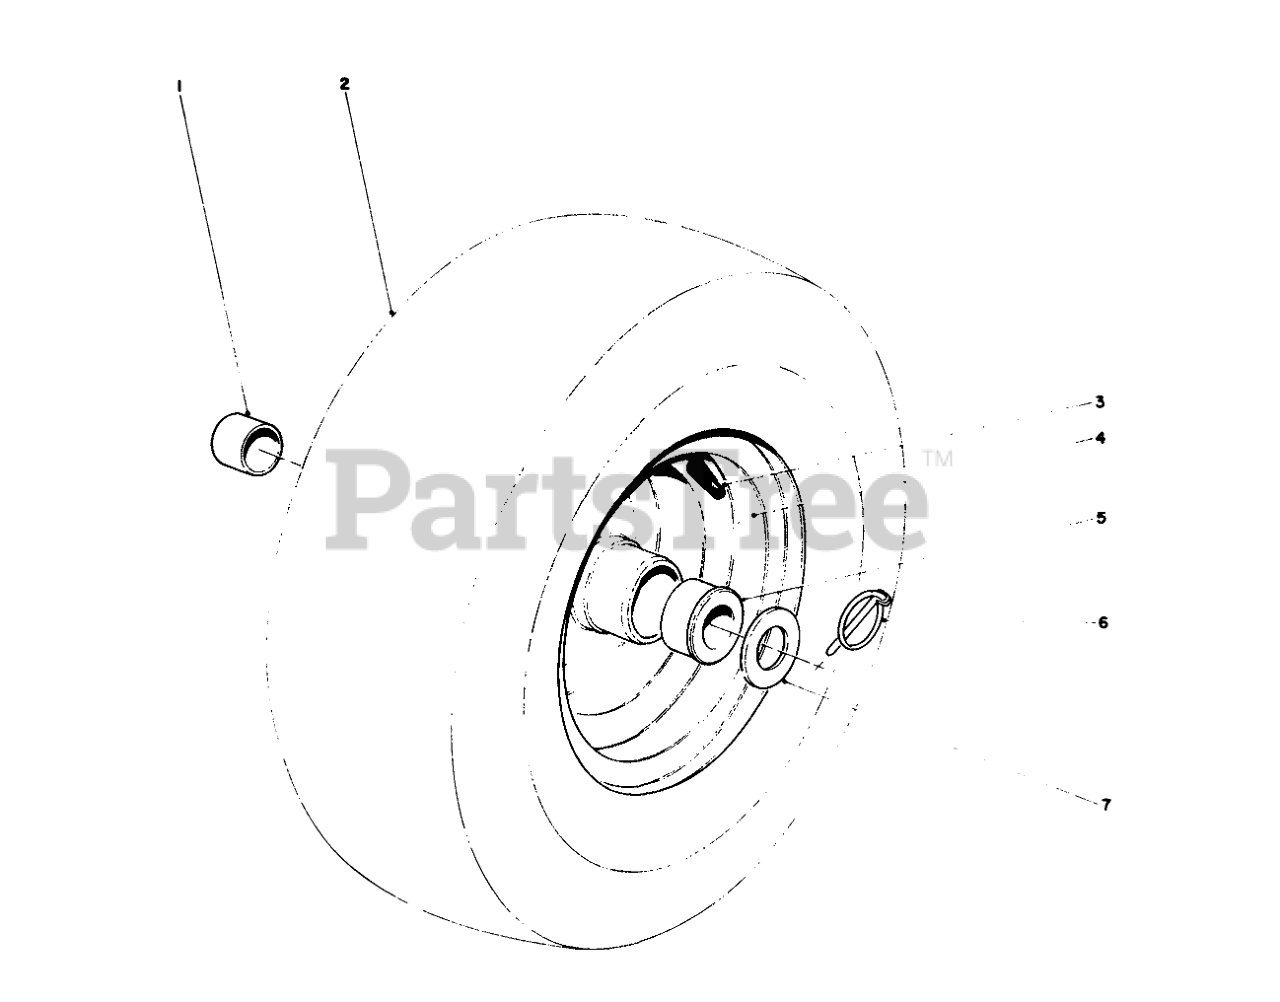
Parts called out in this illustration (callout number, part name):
1	.877ID X .750LG BSHG
2	Tire
3	STEM-VALVE
4	Wheel & Hub Assembly (Incl. Ref. # 1 & 5)
5	BUSHING
6	PIN-LYNCH
7	WASHER-THRUST
